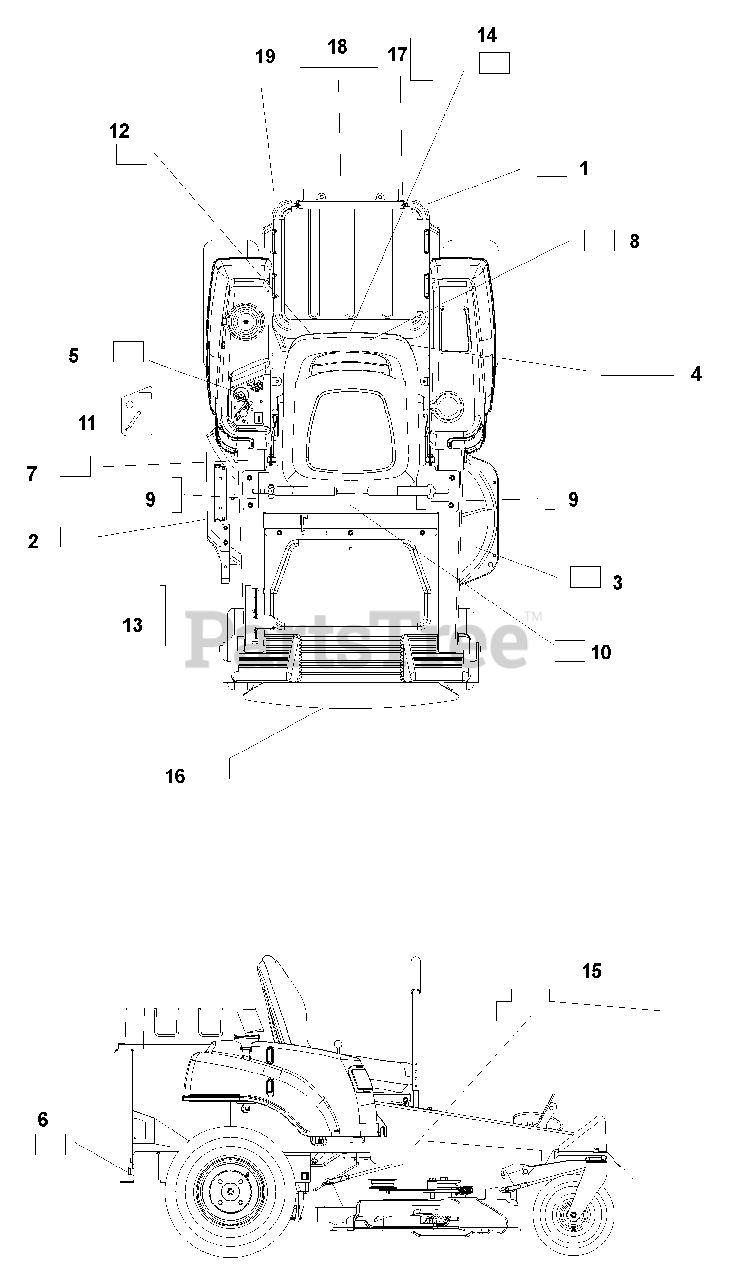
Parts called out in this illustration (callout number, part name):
1	DECAL, PROP 65
2	DECAL, WARNING
3	DECAL, EURO DANGER BELT
4	DECAL, EURO BATTERY WARNING
5	DECAL, START
6	DECAL, DO NOT TOW
7	DECAL, EXITING MOWER
8	DECAL, SERVICE
9	DECAL, MOTION CONTROL
10	DECAL, SAFETY WARNING
11	DECAL, IGNITION CONSOLE
12	DECAL, BELT
13	DECAL, CUTTING HEIGHT
14	DECAL, CUSTOMER RESPONSIBILITY
15	DECAL, MODEL Z38, RIGHT
15	DECAL, MODEL Z38, LEFT
15	DECAL, MODEL Z42, LEFT
15	DECAL, MODEL Z42, RIGHT
16	DECAL, HUSQVARNA 12"
17	DECAL, UTILITY BOX WARNING
18	DECAL, UTILITY BOX PAYLOAD
19	DECAL, PAYLOAD/GASOLINE
